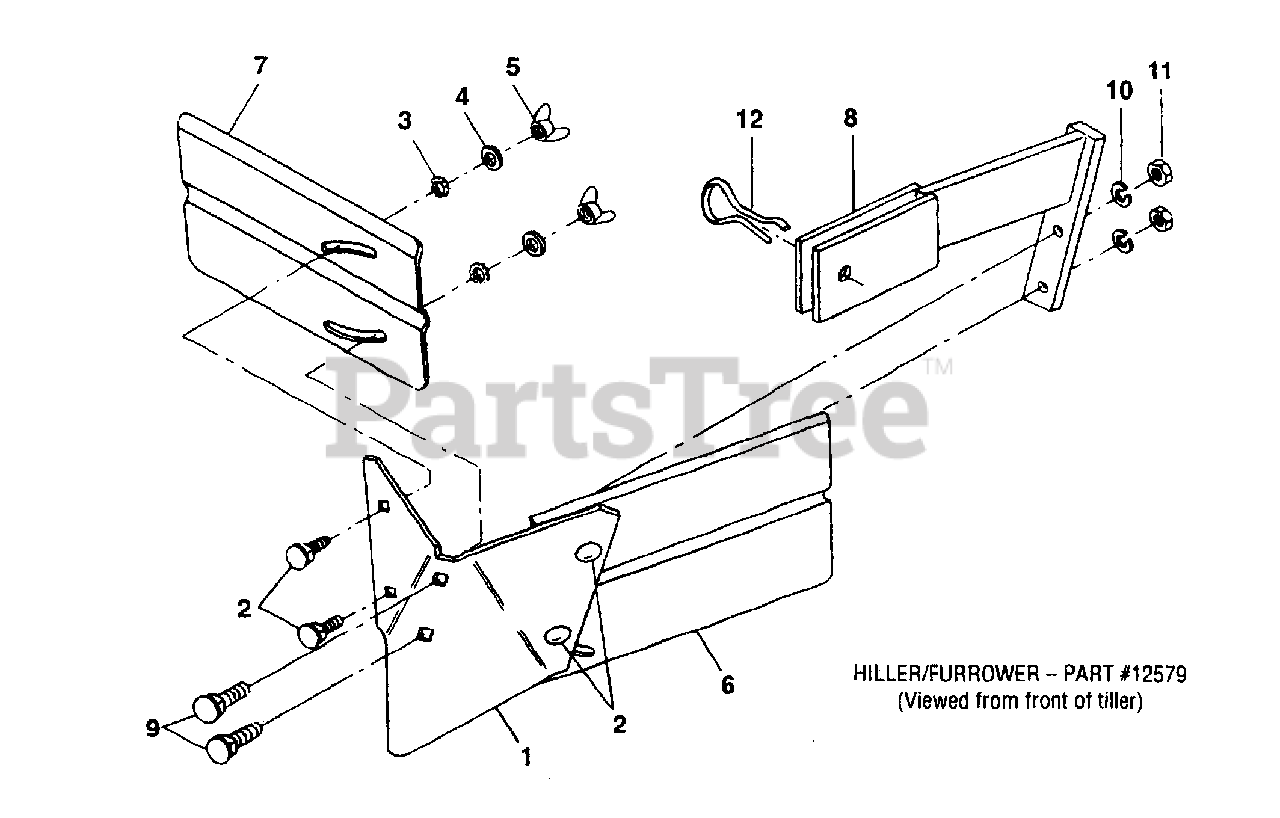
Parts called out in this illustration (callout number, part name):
1	Furrower Blade
2	Carriage Bolt, 5/16-18 x 3/4
3	Star Washer, External Tooth, 5/16
4	Plain Washer, 5/16 S.A.E
5	Wing Nut, 5/16-18
6	Hiller Wing, left
7	Hiller Wing, right
8	Blade Mounting Bracket
9	Carriage Bolt, 3/8-16 x 1-1/2
10	Lockwasher, 3/8, plated
11	Hex Nut, 3/8-16, plated
12	Clinch Pin
